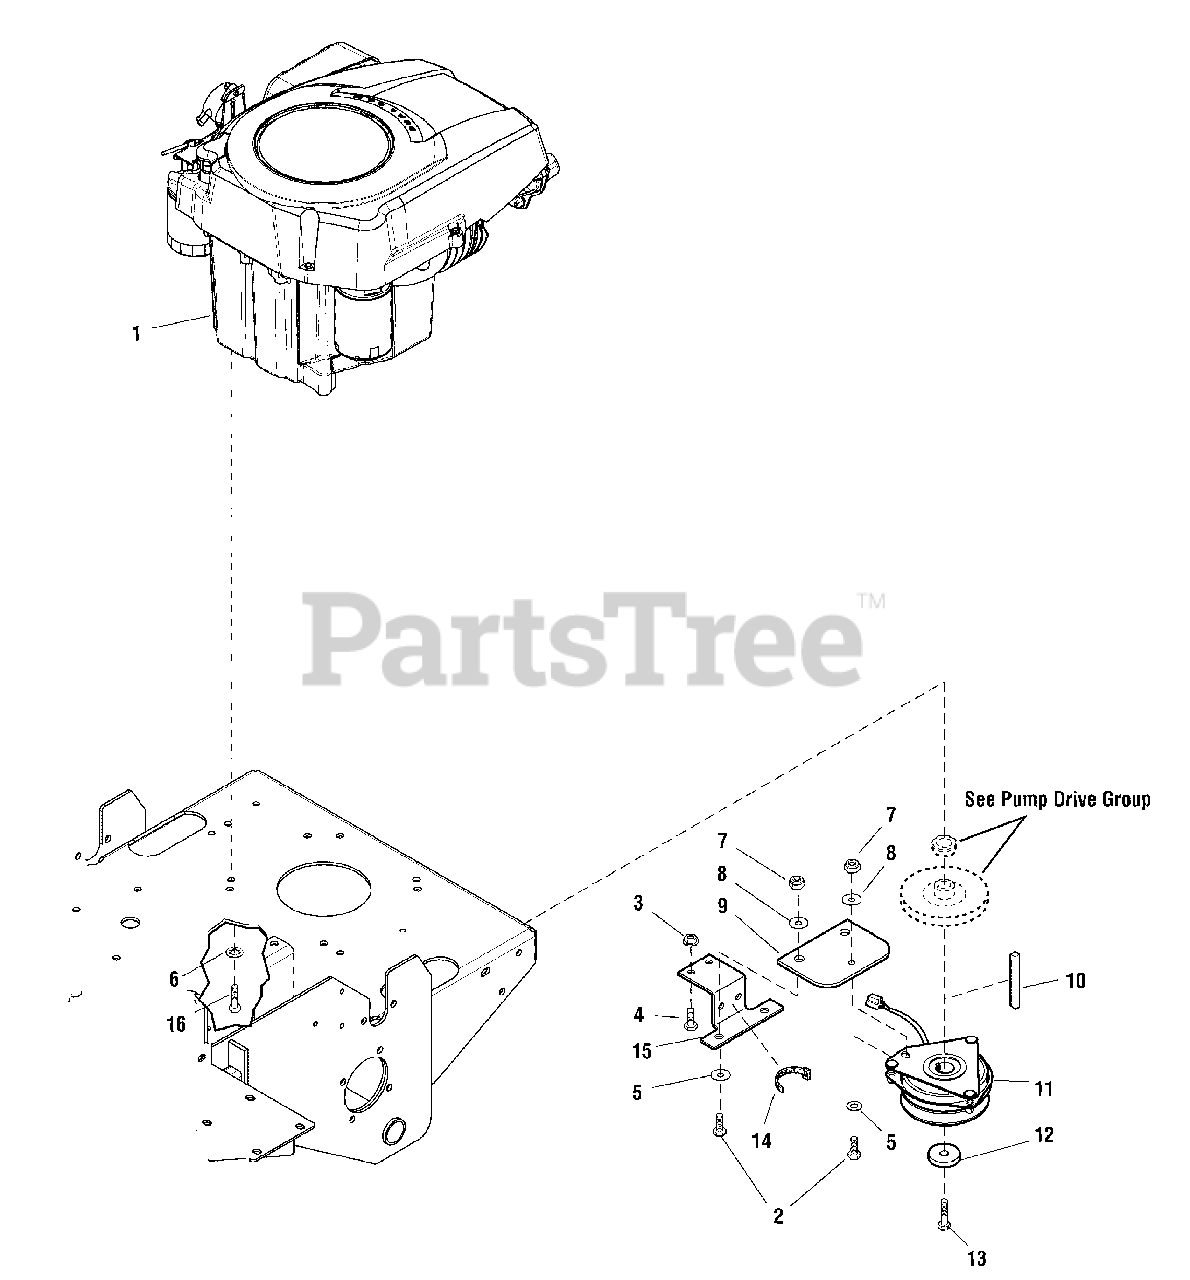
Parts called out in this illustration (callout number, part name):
1	ENGINE, 18HP KOHLER
2	BOLT, 5/16-18 X 1
3	NUT, HEX NYLOCK FLANGE, 5/16-18
4	BOLT, 5/16-18 X 3/4
5	WASHER, SAE, 5/16
6	WASHER, 5/16 INT TOOTH LOCK
7	NUT, HEX NYLON LOCK, 5/16-18
8	WASHER, CLUTCH ANCHOR, 5/16
9	CLUTCH ANCHOR PAD
10	KEY, 1/4 SQ. X 2-1/4
11	CLUTCH, ELECTRIC
12	SPACER, .45 X 1.62 X .37
13	BOLT, CRANKSHAFT, 7/16-20 X 3-1/4"
15	CLUTCH ANCHOR
16	BOLT, M8-1.25 x 35MM
